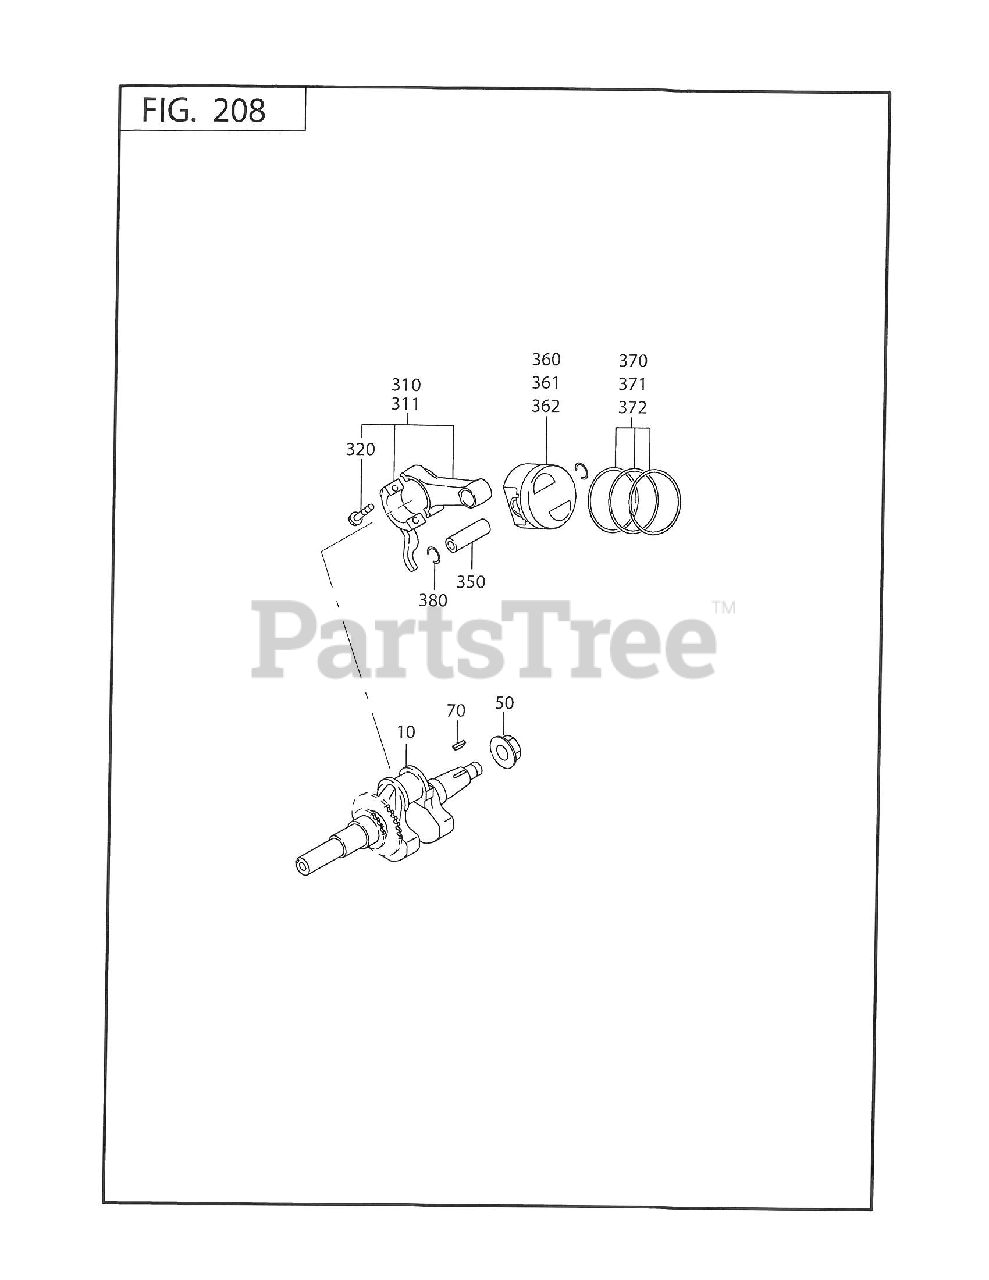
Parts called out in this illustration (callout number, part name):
10	BLOWER HOUSING CP
20	LABEL, TRADEMARK
60	BAFFLE 1 CP, CASE
61	BAFFLE 2, HEAD
210	RECOIL STARTER AY
220	BOLT AND WASHER AY
